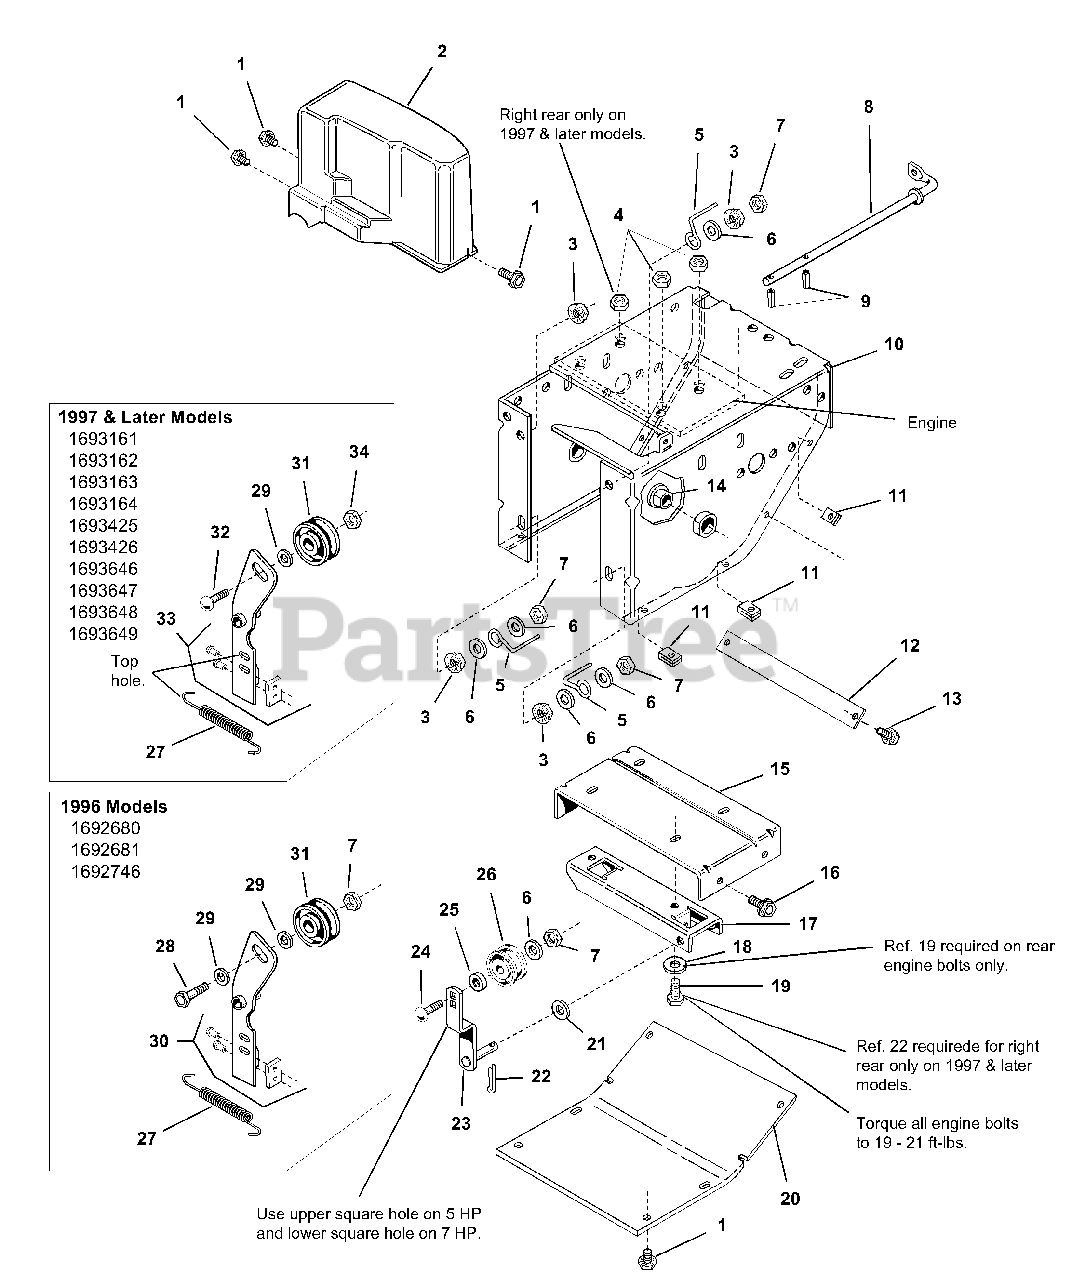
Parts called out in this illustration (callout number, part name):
1	SCREW, Taptite, 1/4-20 x 1/2
2	COVER, Belt,
3	NUT, Hex, Flange, Locking, 3/8-16
4	NUT, Hex, Flange Whizlock, 5/16-18
5	GUIDE, Belt
6	WASHER, Flat,
7	NUT, Hex, Jam, Center-lock, 3/8-16,
9	PIN, Spring
10	FRAME,
11	NUT, Speed 1/4-20
12	TIE BAR SUPPORT
13	SCREW, Taptite, #10-24 x 1/2
15	FRAME BRACKET
16	SCREW, Taptite, 5/16-18 X 1/2
17	SUPPORT, Pivot
18	WASHER
19	SCREW, Hex Hd., 5/16-18 x 1,
19	SCREW, Hex Hd., 5/16-18 x 1-3/4
20	COVER, Bottom
21	WASHER, Flat 15/32
22	PIN, Cotter
23	ARM & SHAFT ASSY., Idler
24	BOLT, Carriage, 3/8-16 X 1-1/4
26	PULLEY, Idler - Traction Drive
27	SPRING, Extension
28	CAPSCREW, Hex Hd., 3/8-16 X 1-3/4
29	WASHER, 3/8
30	ARM & HUB ASSY., Idler/Brake
31	PULLEY, Idler - Auger Drive
32	BOLT, Carriage, 3/8-16 x 1-3/4
33	ARM & HUB ASSY., Idler/Brake
34	NUT, Hex, Flange, Locking, 3/8-16
